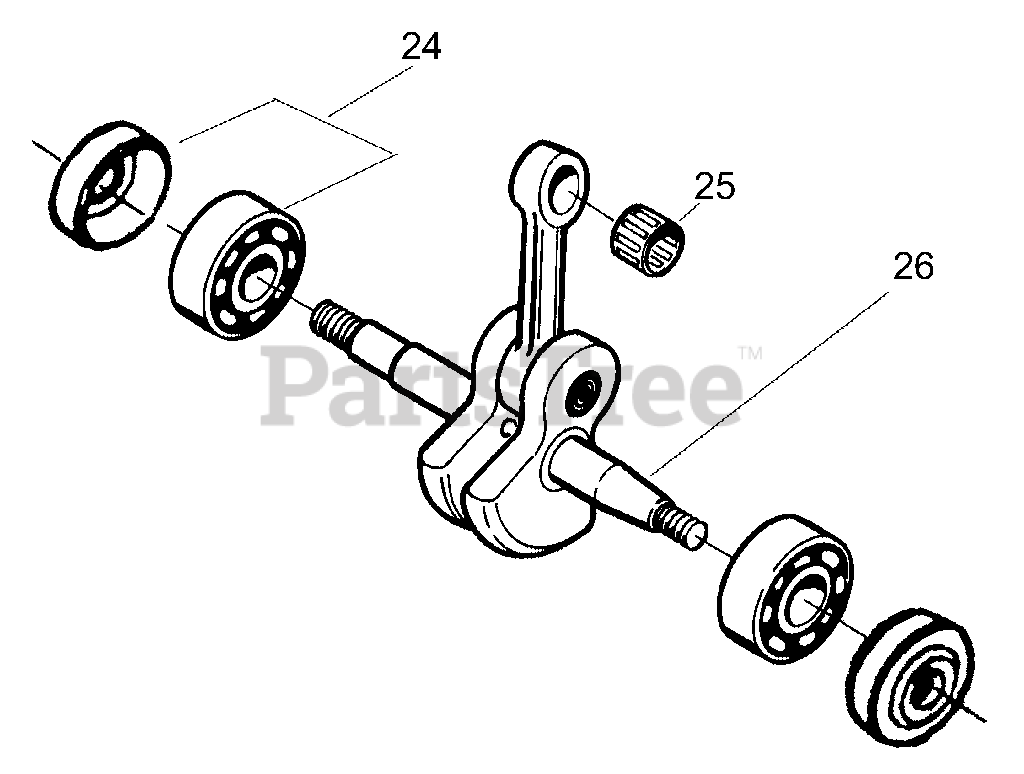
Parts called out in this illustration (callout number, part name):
24	Assy. - Bearing and Seal
25	Piston Pin Bearing
26	Crankshaft & Rod Assembly
